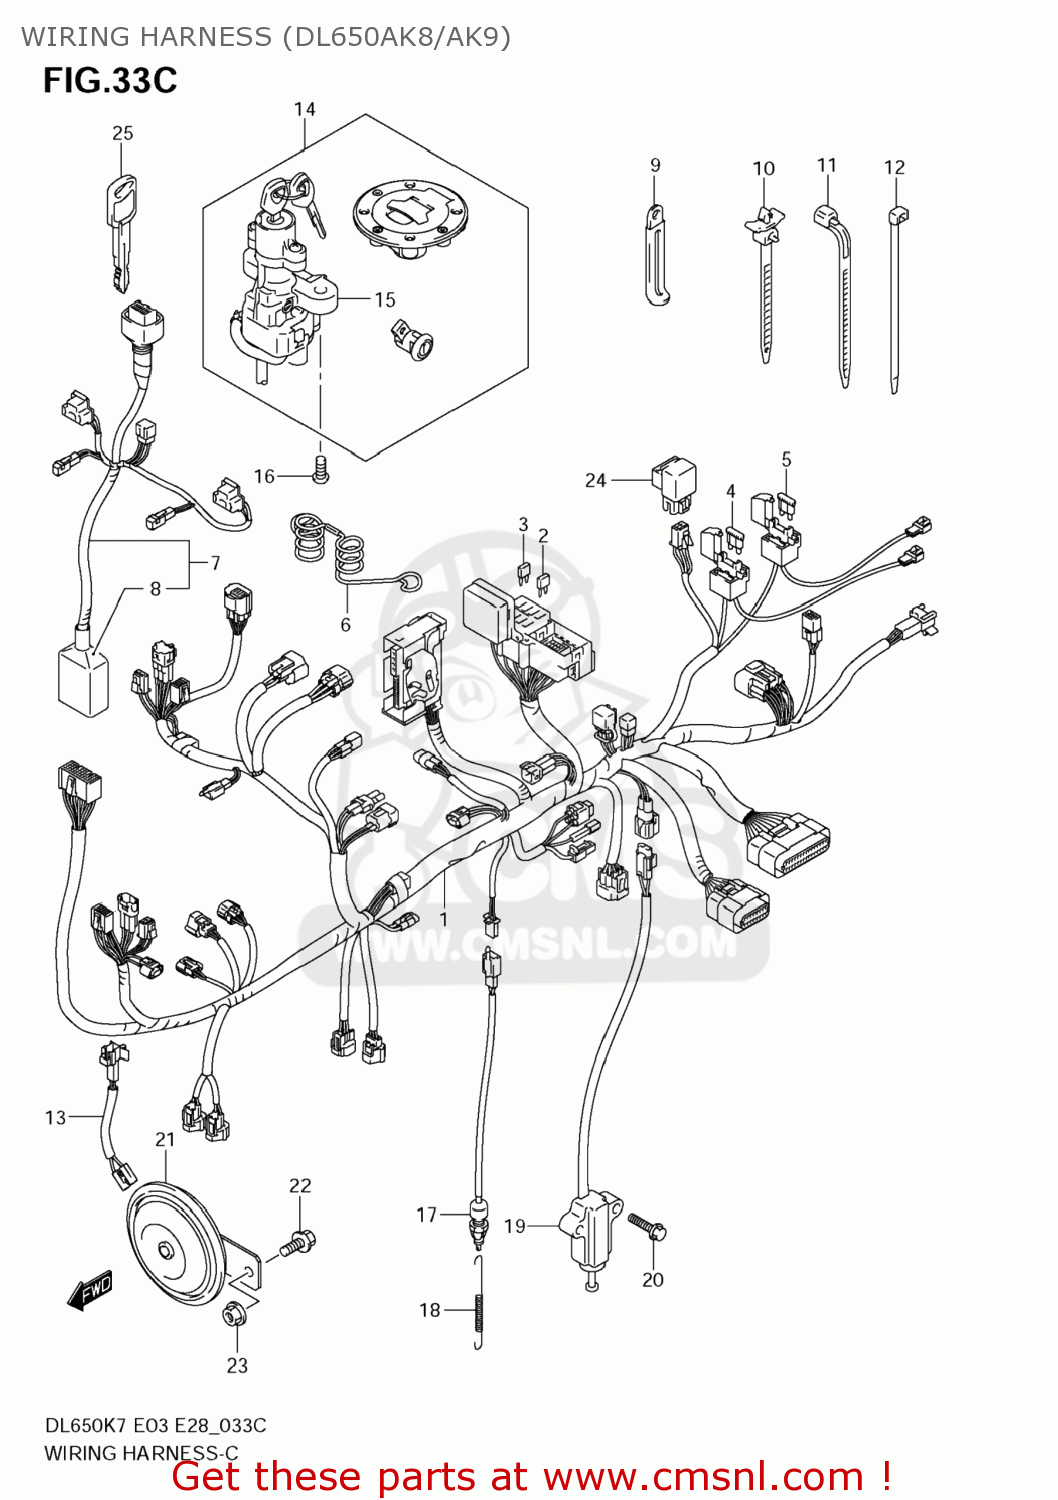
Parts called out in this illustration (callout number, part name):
1	HARNESS,WIRING NO.1
2	FUSE(10A)
3	FUSE(15A)
4	FUSE(40A)
5	FUSE (25A)
6	GUIDE,WIRING HARNESS
7	HARNESS,WIRING NO.2
8	COVER,CONNECTOR
9	CLAMP(L:45)
10	CLAMP(L:120)
11	CLAMP(L:95)
12	CLAMP(L:145)
13	WIRE,HORN LEAD
14	LOCK SET
15	LOCK ASSY,STEERING
16	BOLT(8X20)
17	SWITCH ASSY,STOP LAMP
18	SPRING
19	SWITCH ASSY,SIDE STAND
20	BOLT
21	HORN ASSY
22	BOLT
23	NUT
24	RELAY ASSY
25	KEY,BLANK
